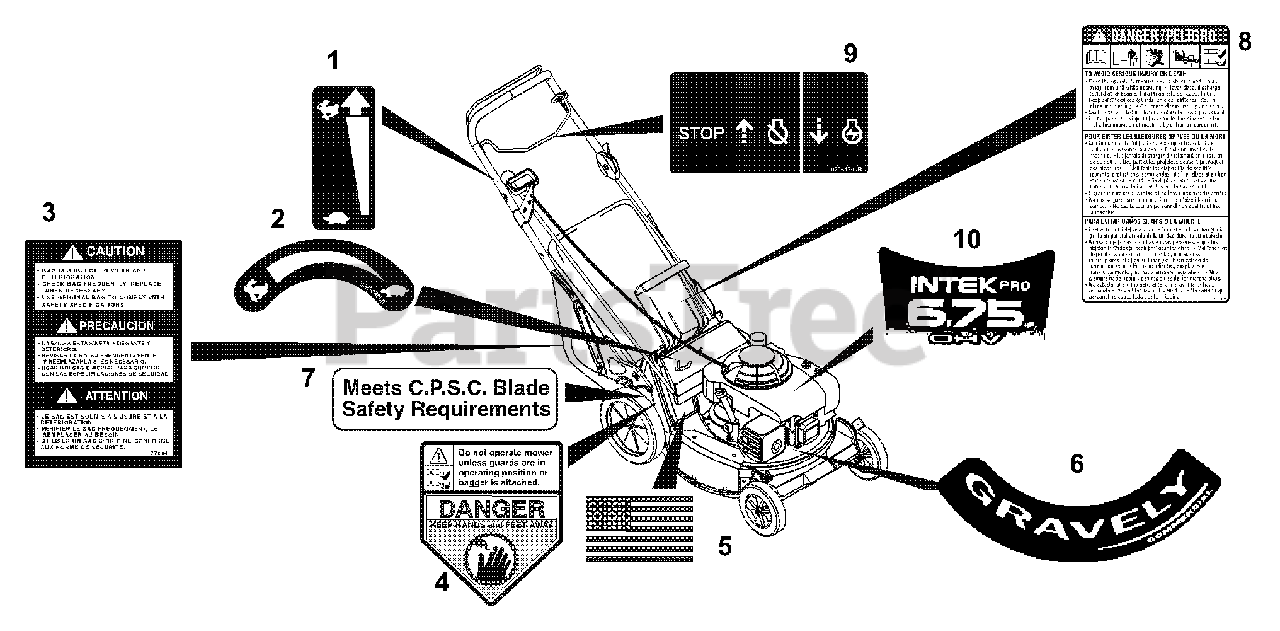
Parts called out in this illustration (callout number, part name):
1	DECAL-SPEED CONTROL
2	DECAL, TURTLE & RABBIT
3	LABEL - BAGGER 21"
4	DECAL, CPSC DANGER
5	DECAL, AMERICAN FLAG
6	DECAL-COMMERCIAL
7	DECAL, C.P.S.C. BLADE SAFETY
8	DECAL, BILINGUAL DANGER
9	DECAL - ENGINE CONTROL
10	DECAL, B&S INTEK 6.75HP
